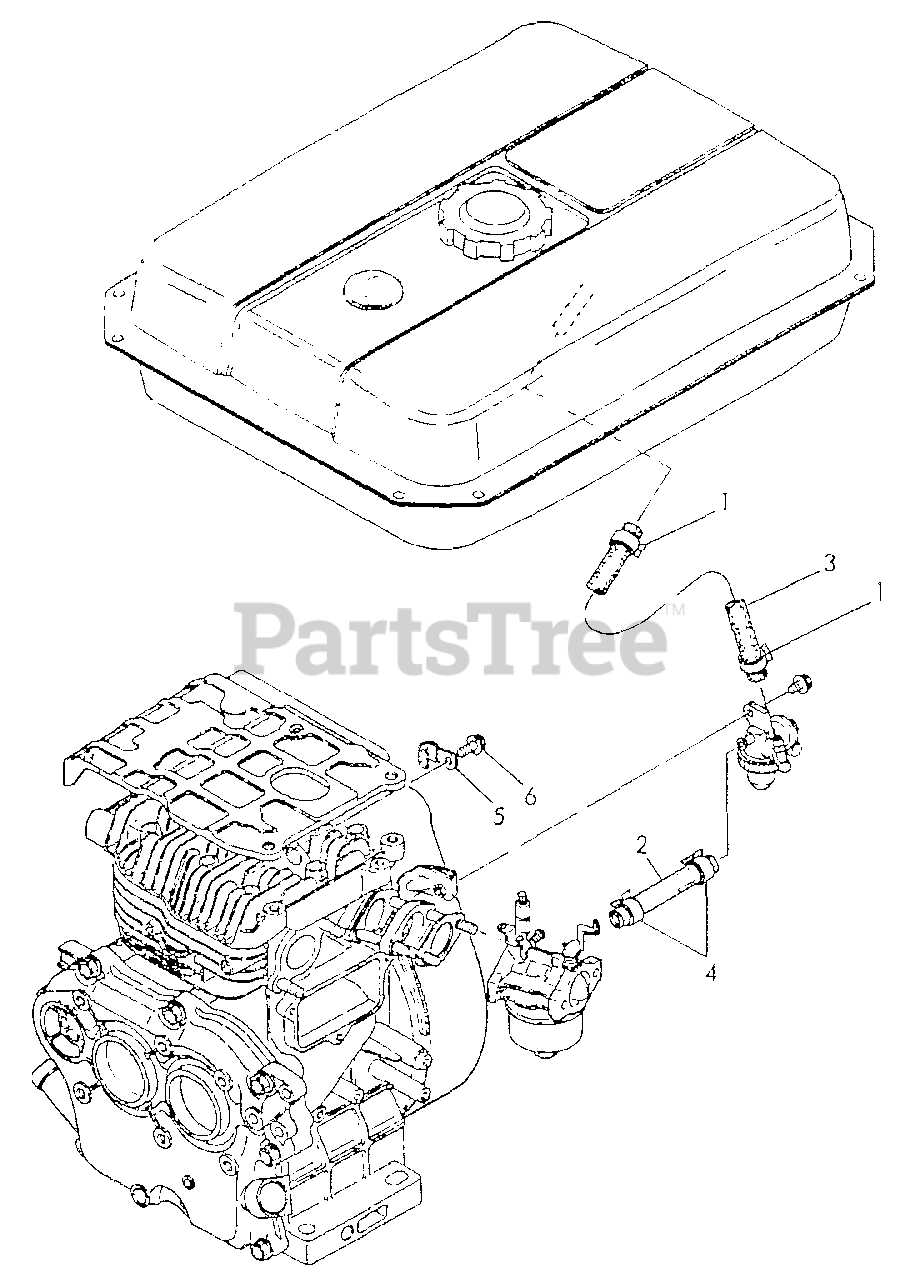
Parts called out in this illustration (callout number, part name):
1	CLAMP, HOSE
2	PIPE - FUEL
3	PIPE - FUEL
4	CLAMP
5	CLAMP
6	BOLT - 6X8 -- PLATED
